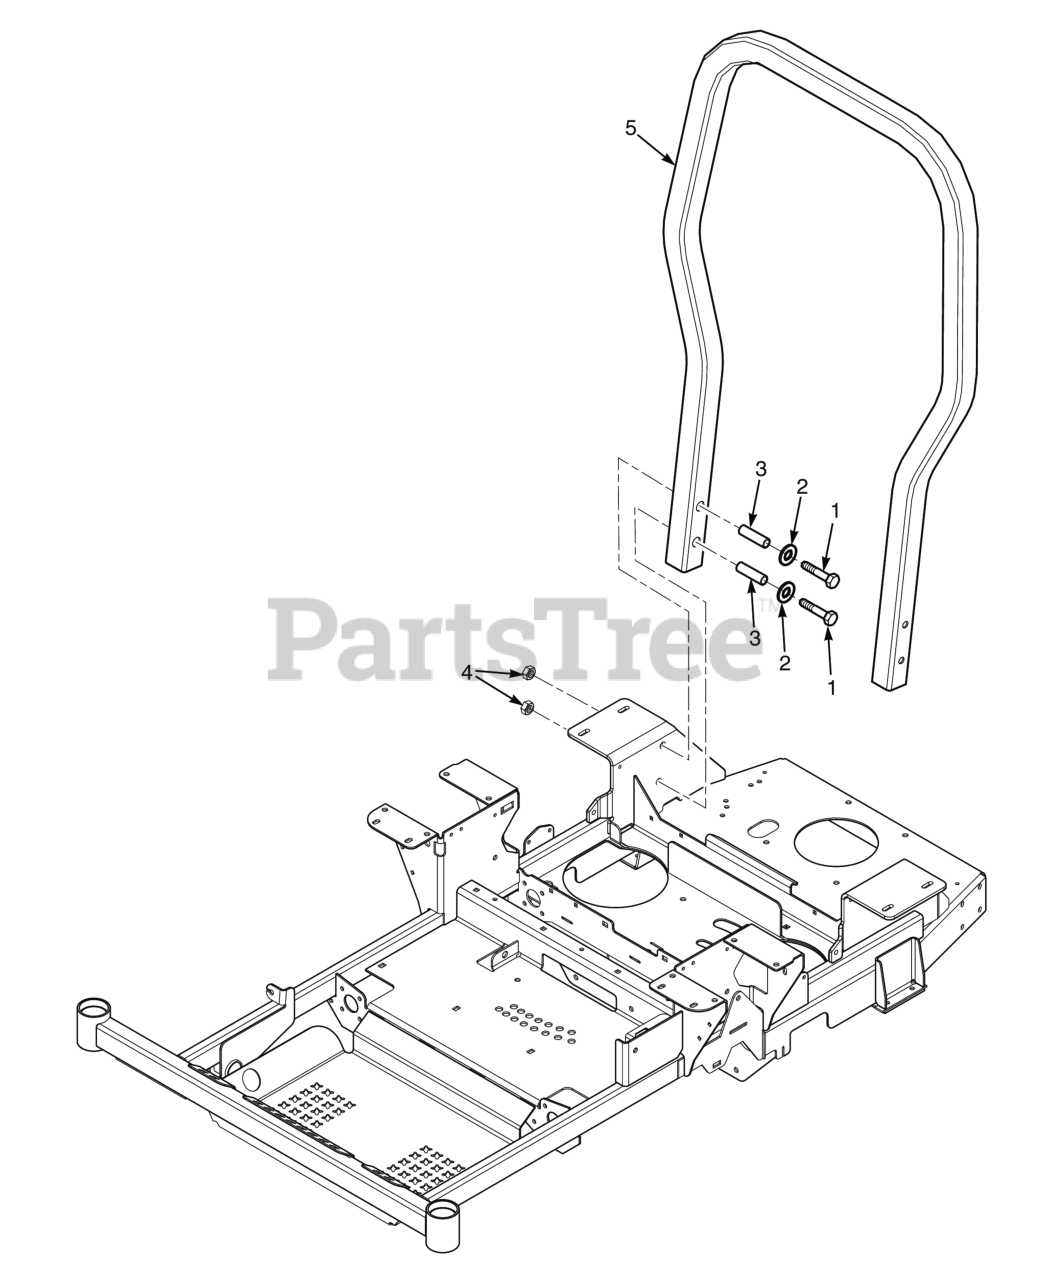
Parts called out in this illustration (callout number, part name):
1	Bolt, Hex Head 1/2-13 x 3-1/4" Gr. 8
2	Flatwasher, 1/2 - .531 x 1.062 x .095
3	Bushing, SFZ ROPS
4	Nut, Elastic Stop 1/2-13, (STT-52 & STTII-52)
5	ROPS, SFZ48, SFZ52
